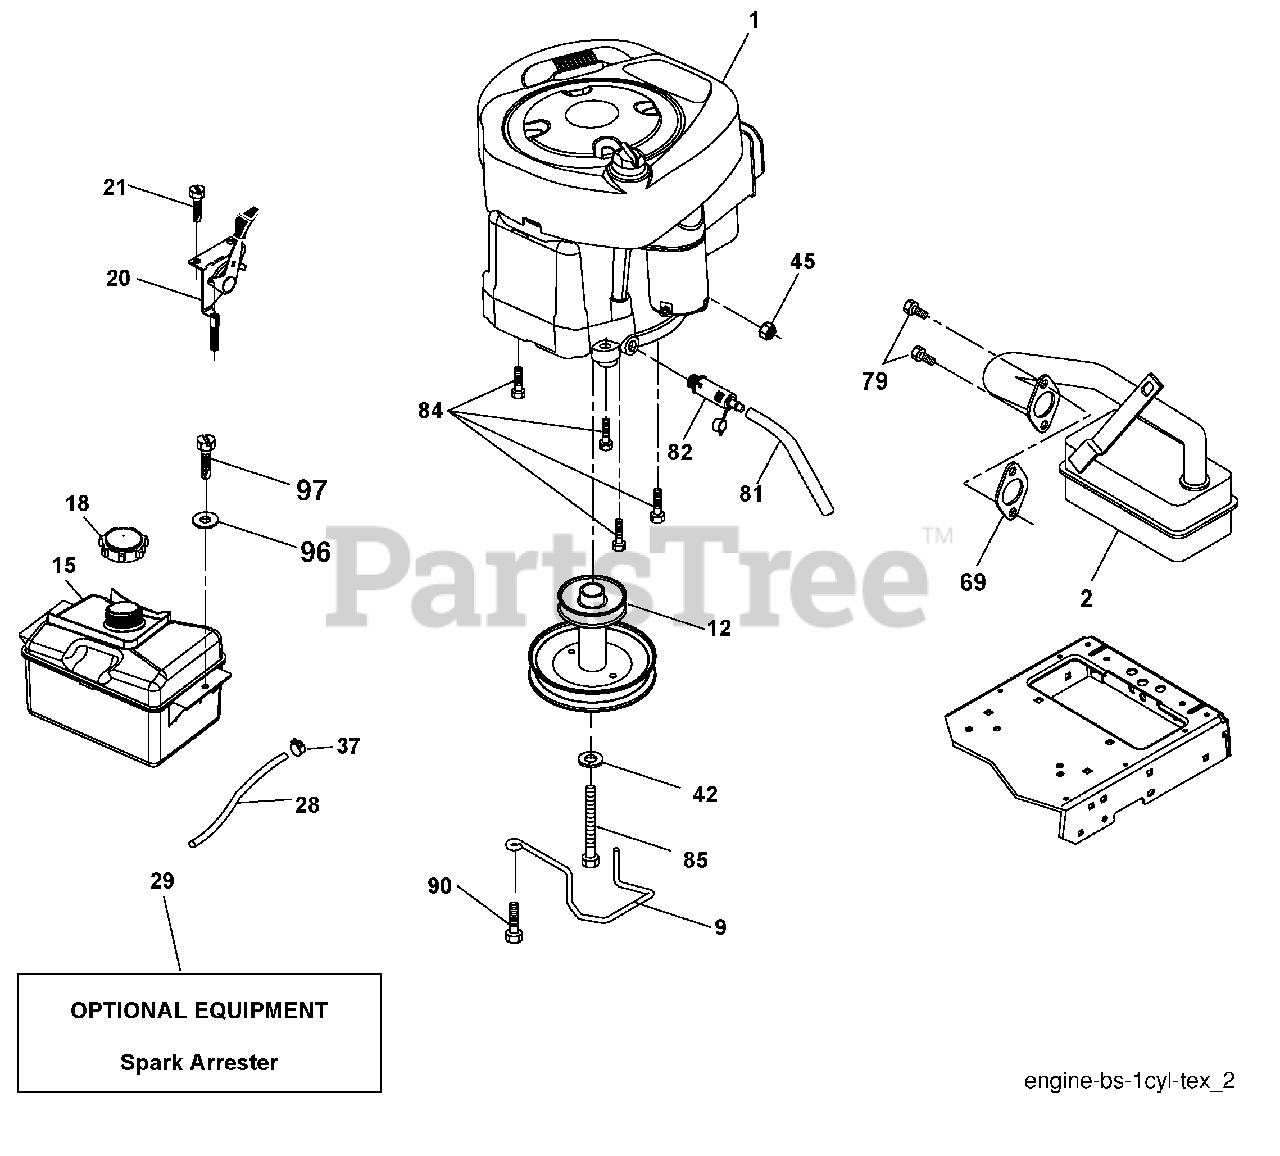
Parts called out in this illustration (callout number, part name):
2	Muffler
9	Keeper Belt Engine
12	Pulley Engine
15	Tank Fuel
18	Cap Asm
20	Control Throttle
21	Screw 10 x 3/4 Single Lead-Hex
28	Fuel Line
29	Spark Arrester Kit
37	Clamp Hose
42	Washer Lock 7/16
45	Nut Keps Hex 1/4-20 unc
69	Gasket
79	Screw Socket HD 5/16-18 x .75
81	Tube Drain Oil Easy
82	Plug Drain Oil
84	Screw 3/8-16 x 1-1/4
85	Bolt 7/16-20 x 4 x Gr. 5-1.5
90	Screw 3/8-16 x 1
96	Washer 9/32 x 7/8 x 16 Ga.
97	Screw 1/4-20 x 3/4
